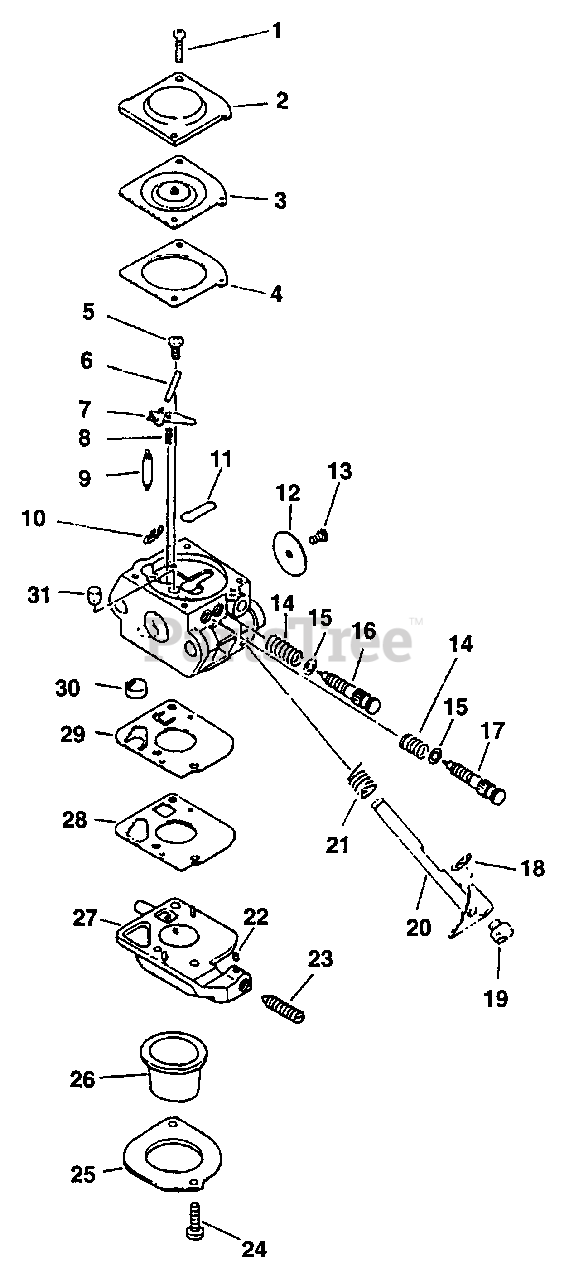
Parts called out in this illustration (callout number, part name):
2	COVER, METERING DIAPHRAGM
3	DIAPHRAGM
4	GASKET, METERING
6	PIN
7	LEVER, METERING
8	SPRING
9	VALVE, NEEDLE
11	PLUG, WELCH
12	VALVE, THROTTLE
14	SPRING, NEEDLE
16	NEEDLE, IDLE
17	NEEDLE, HIGH SPEED
20	SHAFT, THROTTLE
21	SPRING, THROTTLE RETURN
22	PIECE, FRICTION
23	SCREW, IDLE ADJUST
25	RETAINER
26	BULB, PURGE
27	BODY ASSY, PURGE
30	STRAINER
31	NOZZLE, CHECK VALVE
